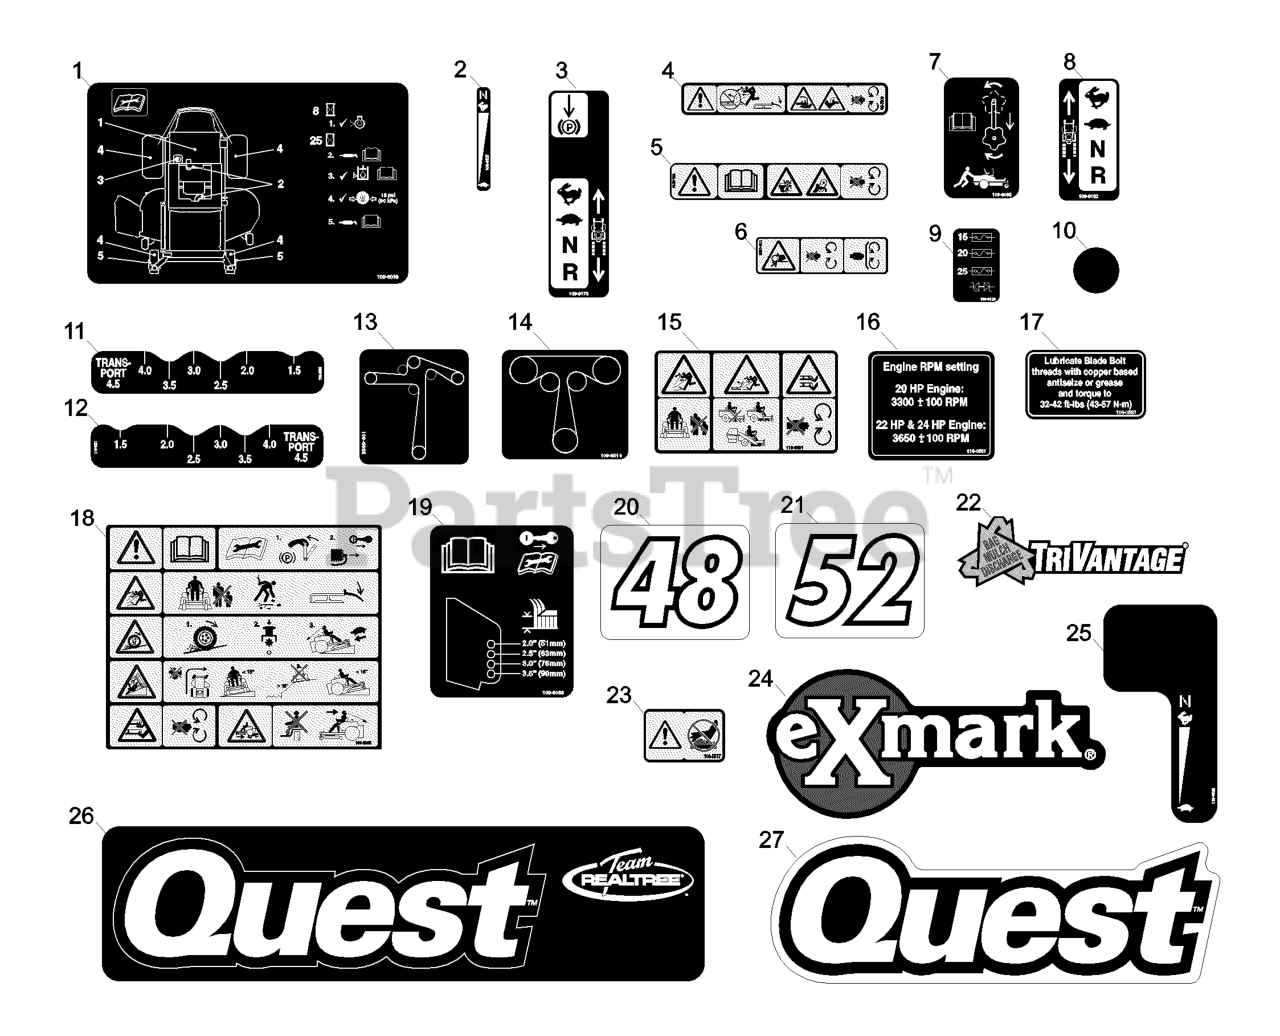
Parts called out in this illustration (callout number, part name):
1	DECAL-SERVICE AID
2	DECAL,THROTTLE/CHOKE
3	DECAL-CONTROL BRAKE
4	DECAL-DANGER
5	DECAL-DANGER
6	DECAL-WARNING, BELT SHIEL
7	DECAL-DRIVE RELEASE
8	DECAL-MOTION CONTROL
9	DECAL-FUSE BLOCK
10	DECAL-HOLE COVER
11	DECAL,HEIGHT OF CUT
12	DECAL,HEIGHT OF CUT
13	DECAL-ROUTING, BELT
14	DECAL-ROUTING, BELT
15	DECAL-DANGER
16	DECAL,ENGINE RPM
17	DECAL,BLADE TORQUE
18	DECAL-SAFETY
19	DECAL-ROLLER, ANTI-SCALP
20	DECAL,DECK 48
21	DECAL,DECK 52
23	DECAL-WARNING
24	DECAL,EXMARK LOGO
25	DECAL,THROTTLE CHOKE 42
26	DECAL,QUEST REALTREE
27	DECAL,QUEST LOGO
